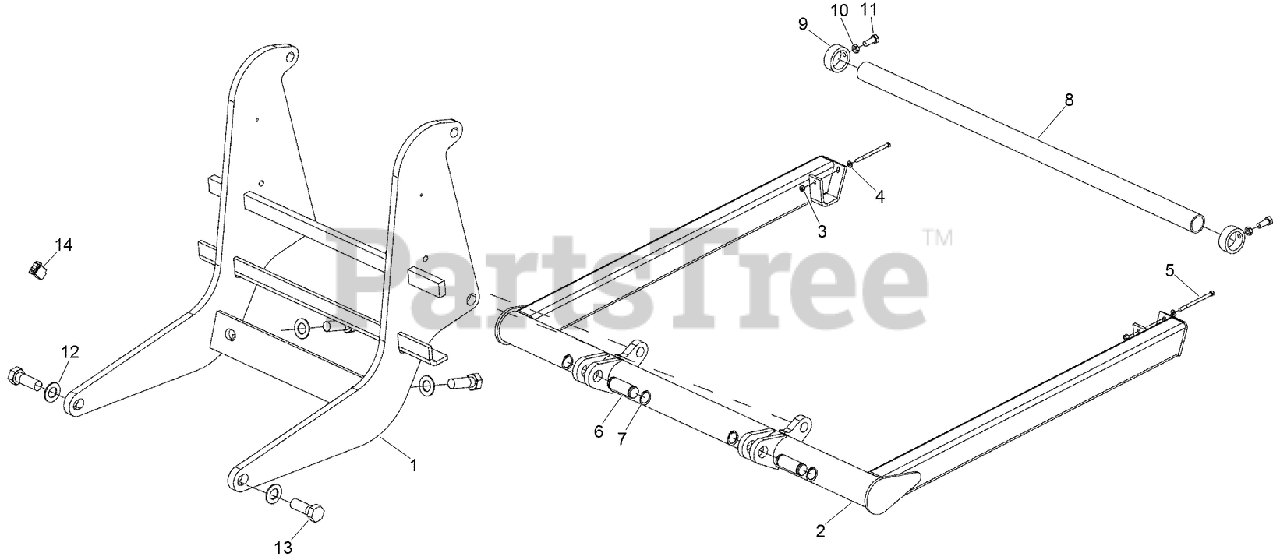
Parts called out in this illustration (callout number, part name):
1	FRAME WELDMENT - Reel Carrier Mtg
2	WELDMENT - Arm, Reel Carrier
3	NUT-HEX
4	WASHER-FLAT
5	BOLT-Hex Hd, 3/8 NC x 5-1/4 inch GR5
8	SPINDLE - Reel Carrier
9	COLLAR-REEL
10	NUT-HEX, JAM
11	BOLT-Hex Hd 5/8 x 1-1/2 GR5 ZND
14	SWITCH-ROCKER, 2 POLE
